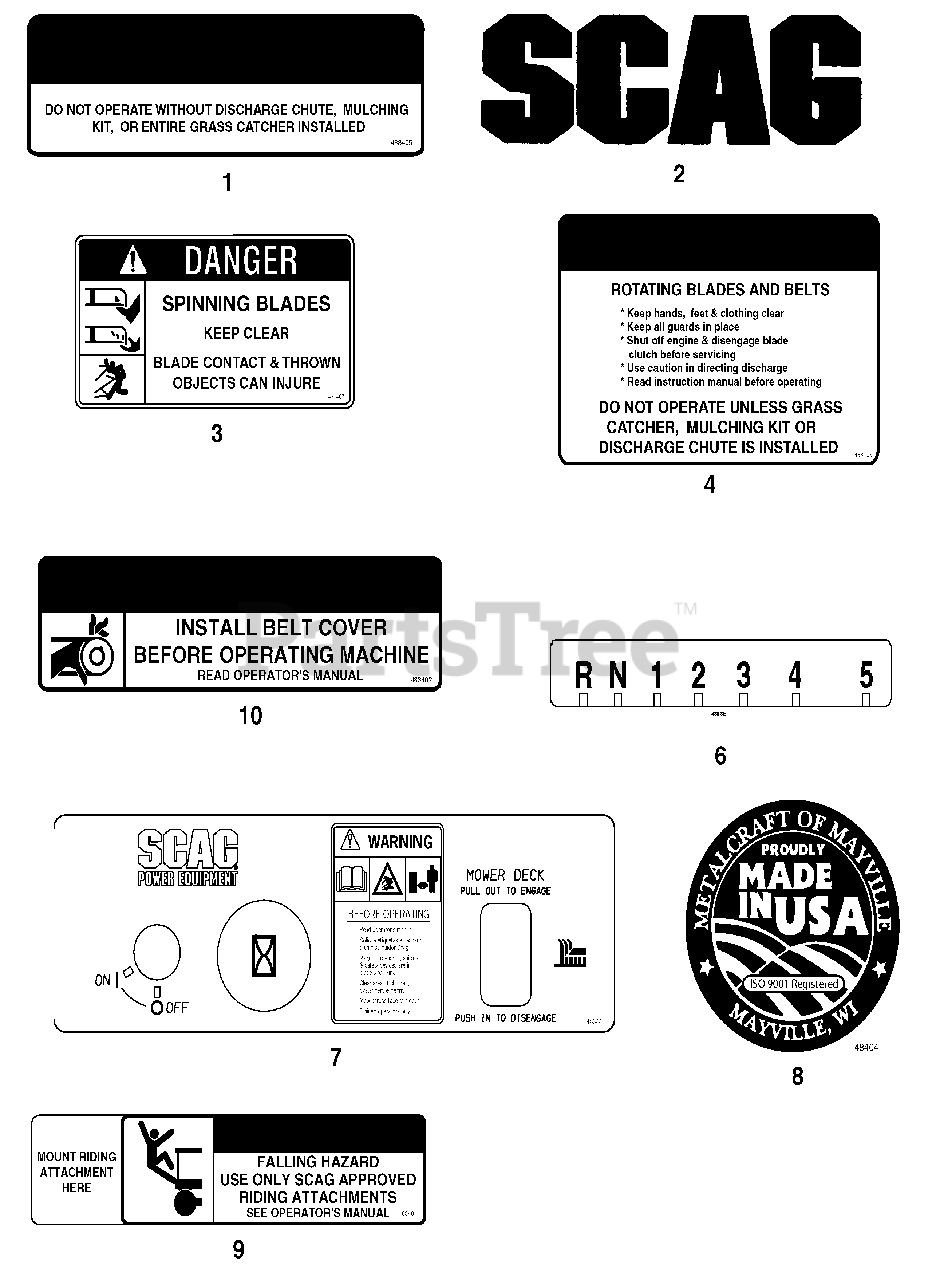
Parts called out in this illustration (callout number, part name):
1	Decal, Discharge Chute
2	Decal, Scag Logo
3	Decal, Danger-Spinning Blades
4	Decal, Warning-Rotating Blades
6	Decal, Shift Index
7	Decal, Instrument Panel - Rear
8	Decal, Metalcraft - Made in USA
9	Decal, Sulky Attachment
10	Decal, Belt Cover
